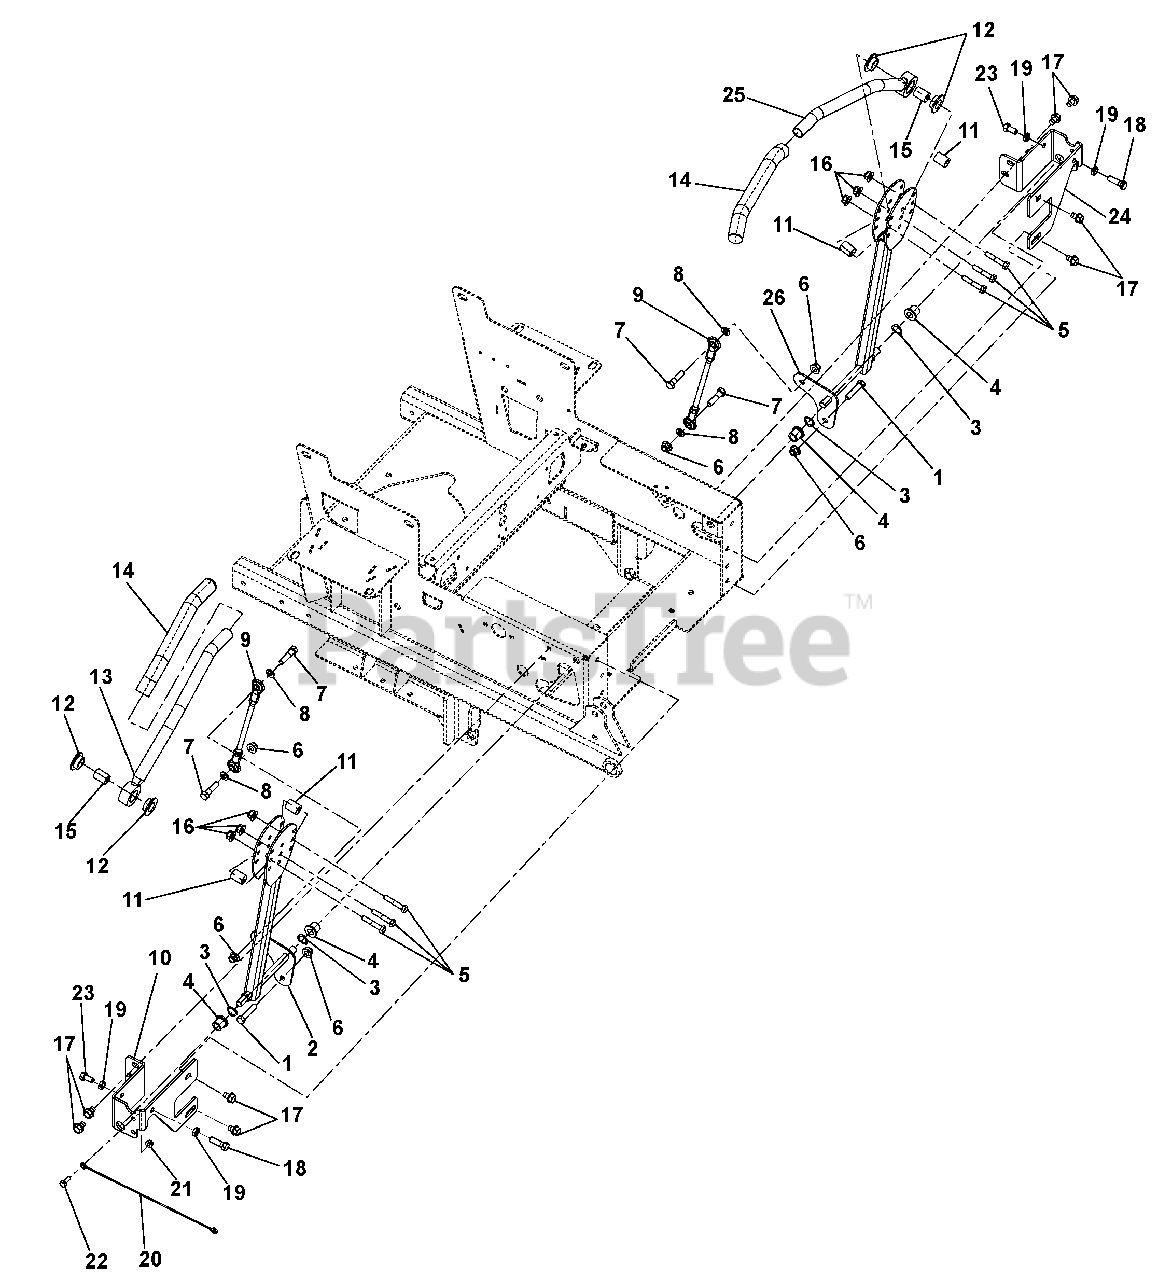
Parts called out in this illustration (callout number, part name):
1	Bolt, Hex .38-16 x 2.00 Full Thread
2	Weldment, Right Hand Control
3	Wave Washer .640 x .875 x .125 Free Height
4	Bushing, Flange .515 x .750 x .745 x 1.00 Nylon
5	Bolt, Hex .31-18 x 1.75 Grade 5
6	Nut, .38-16 Nyloc Flange
7	Bolt, Hex .38-16 x 1.50 Grade 5
8	Washer, Locking .38 x .094 Regular
9	Assembly, Steering Linkage
10	Bracket, Right Hand Steering Stop
11	Eccentric
12	Bushing, Flange .762 x 1.48 x .44 Nylon
13	Handle Weldment Right Hand
14	Grip, Handle
15	Spacer, .328 x .76 x 1.01
16	Nut, .31-18 Nyloc Flange
17	Screw, Tapping .38-16 x .50 Hex Washer Head Thread Rolling
18	Bolt, Hex .38-16 x 1.25 Grade 5
19	Nut, Hex-Jam .375-16
20	Cable, 12.0 Lanyard, Nylon
21	Nut, .25-20 Nyloc Flange
22	Bolt, Hex .25-20 x .75 Grade 5
23	Bolt, Hex .38-16 x .75 Grade 5
24	Bracket, Left Hand Steering Stop
25	Weldment, Handle Left Hand
26	Weldment, Left Hand Control
